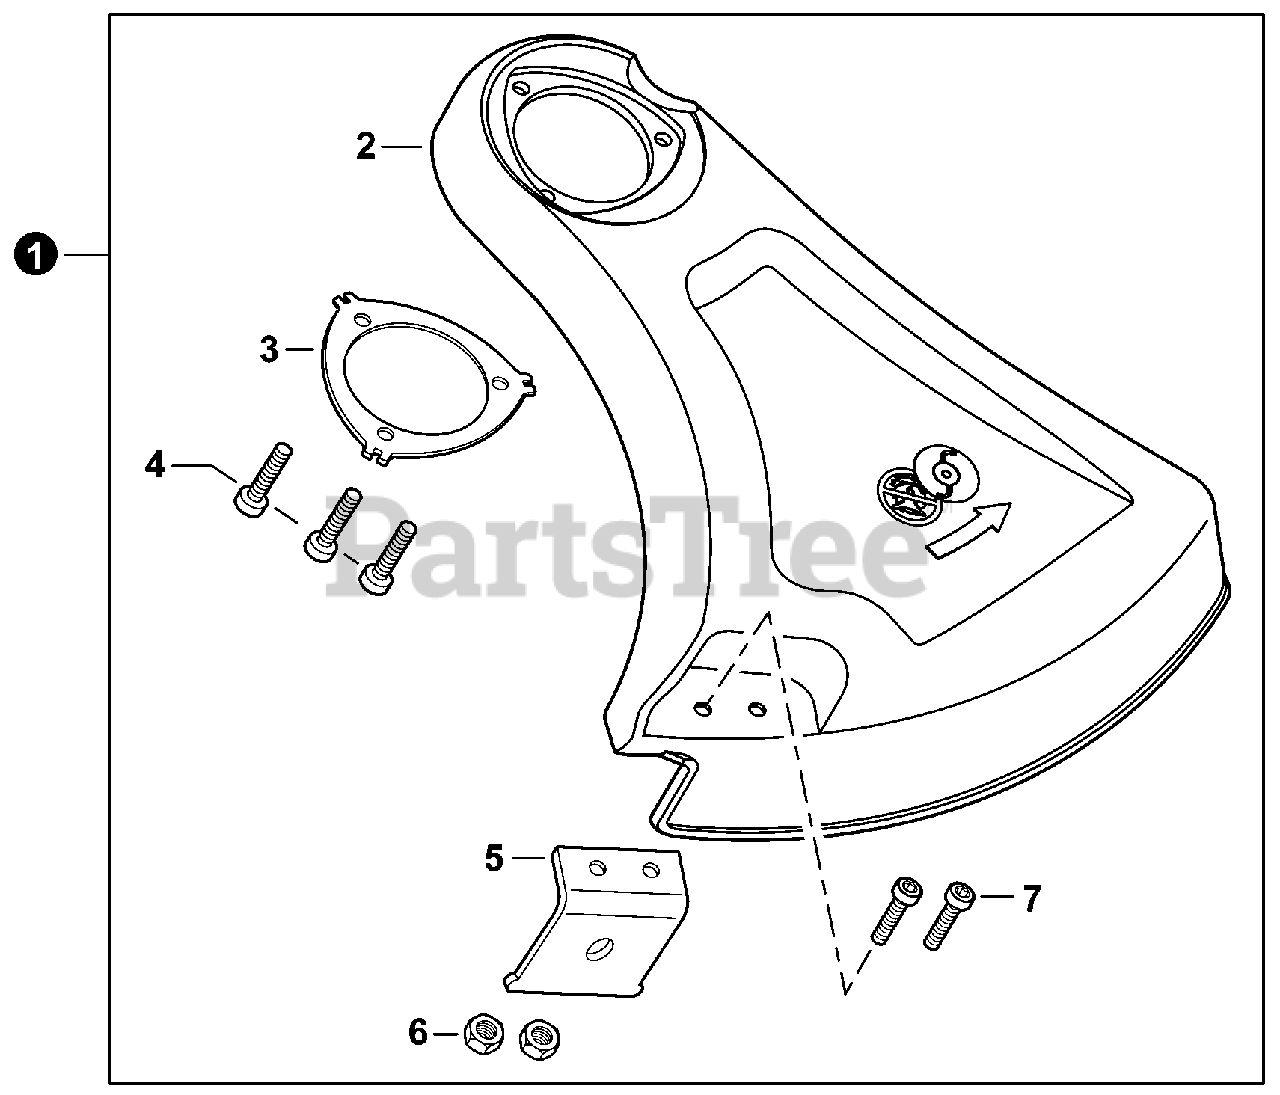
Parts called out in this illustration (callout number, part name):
1	DEBRIS SHIELD ASSY
2	SHIELD, DEBRIS
3	PLATE, SHIELD
4	BOLT, TORX 5×16
5	CUTTER, LINE
6	NUT M5
7	BOLT, TORX 5×12
